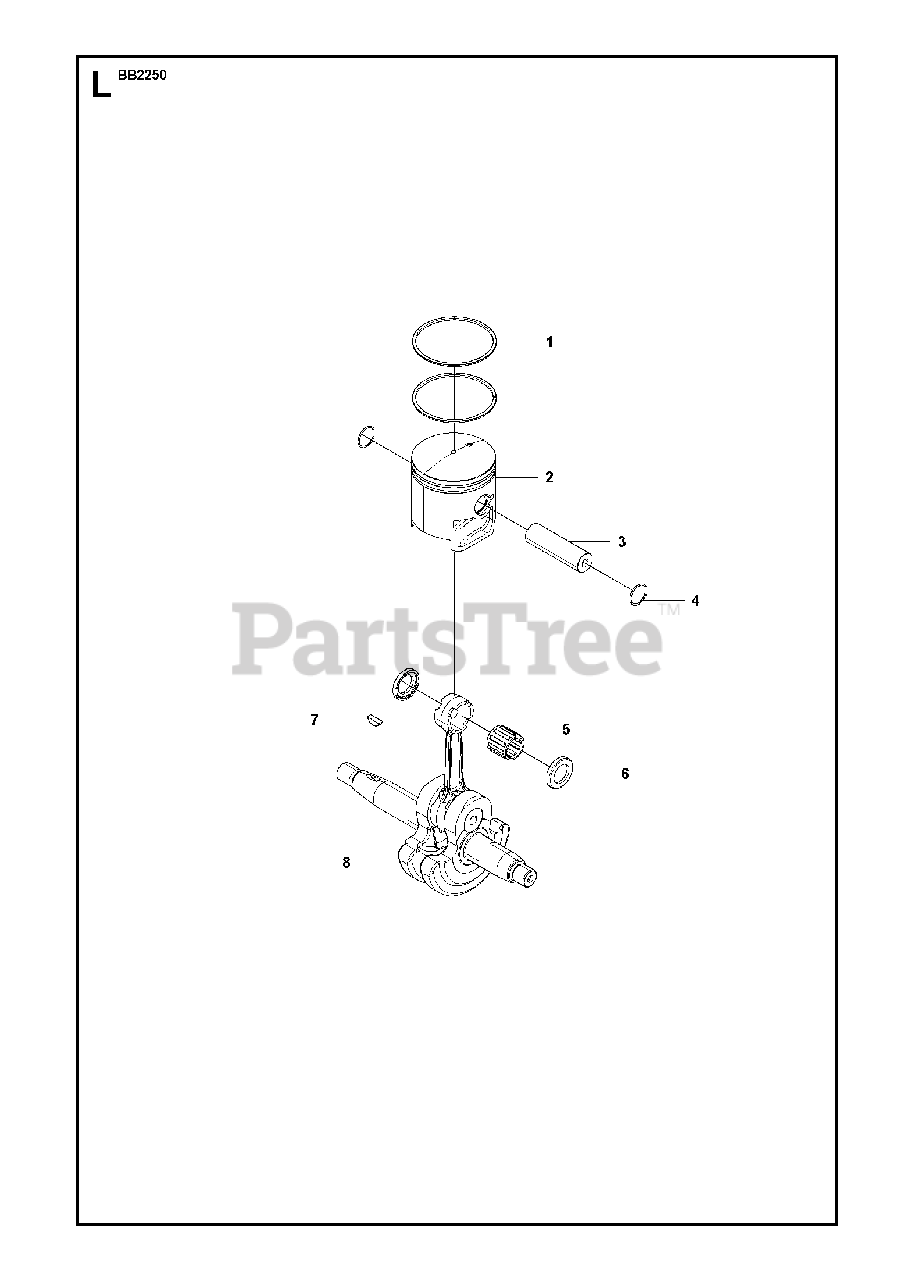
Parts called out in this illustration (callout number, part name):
1	PISTON RING
3	PISTON PIN
4	SNAP RING
7	KEY
8	CRANKSHAFT
